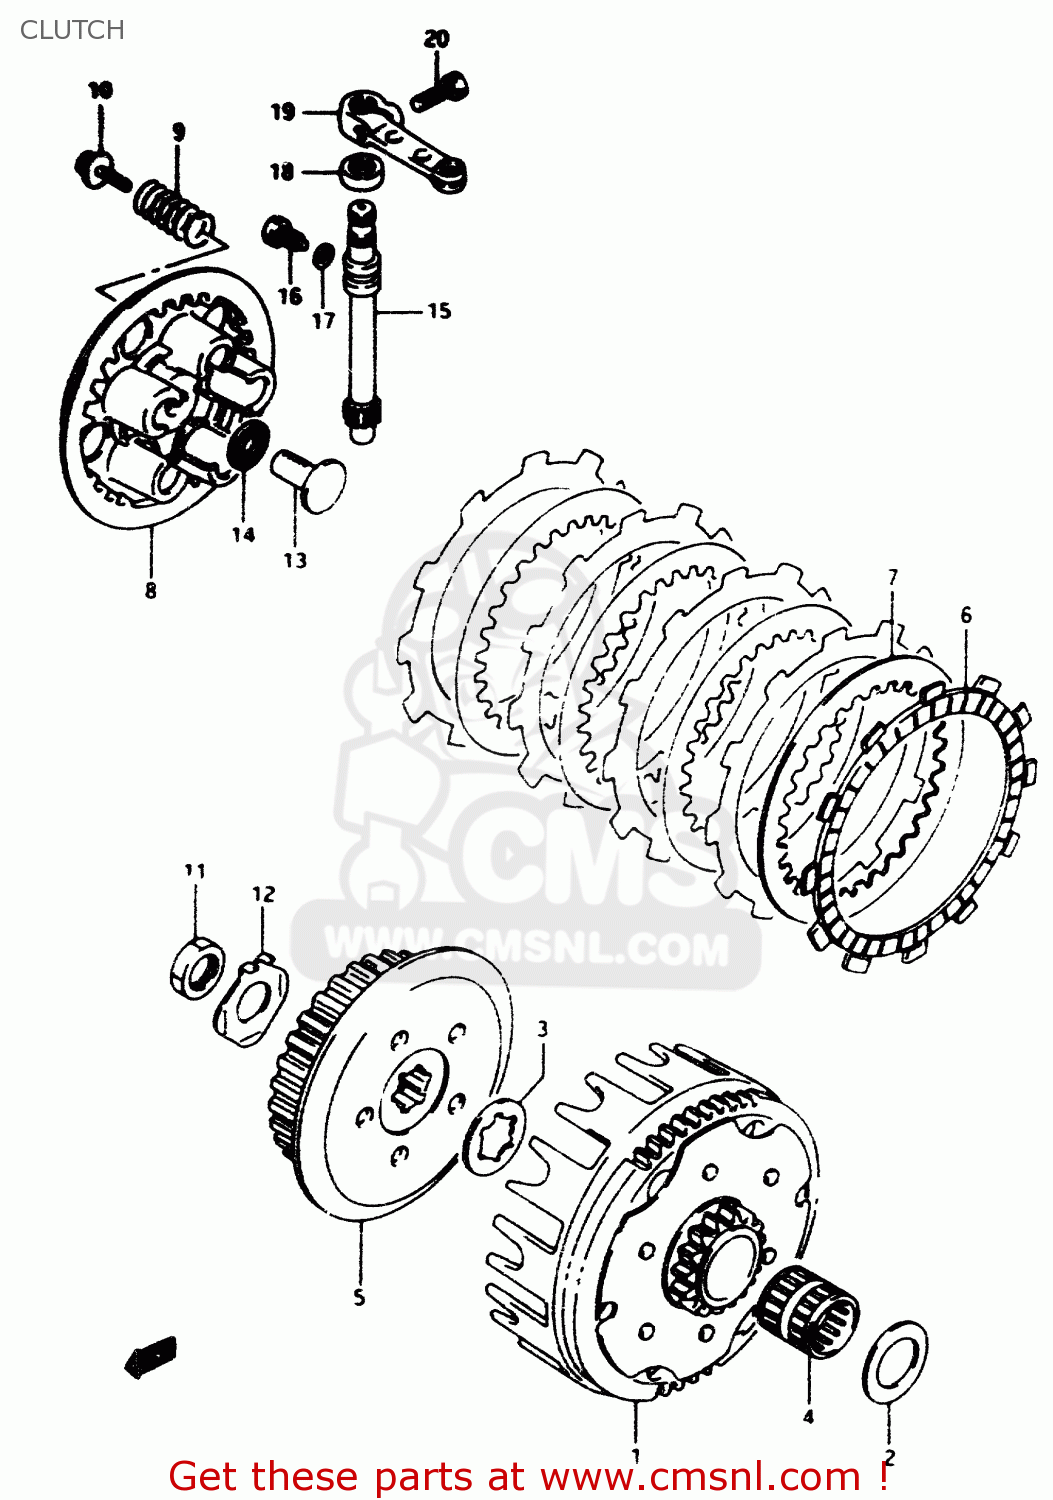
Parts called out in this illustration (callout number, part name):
1	GEAR ASSY,PRI DRIVEN(NT:62/16)
2	WASHER,THRUST
3	WASHER,LOCK
4	BEARING(20X25X26)
5	HUB COMP,CLUTCH SLEEVE
6	PLATE,CLUTCH DRIVE(T:3.0) (NAS)
7	PLATE,CLUTCH DRIVEN(T:2.0) (NAS)
8	DISC,CLUTCH PRESSURE
9	SPRING
10	BOLT 5X16
11	NUT
12	WASHER
13	RACK
14	BEARING(10X22X2.8)
15	PINION,CLUTCH RELEASE
16	BOLT
17	GASKET(6.2X11X1).2 (NAS)
18	SEAL,OIL(10X17X5)
19	ARM,CLUTCH RELEASE
20	BOLT
